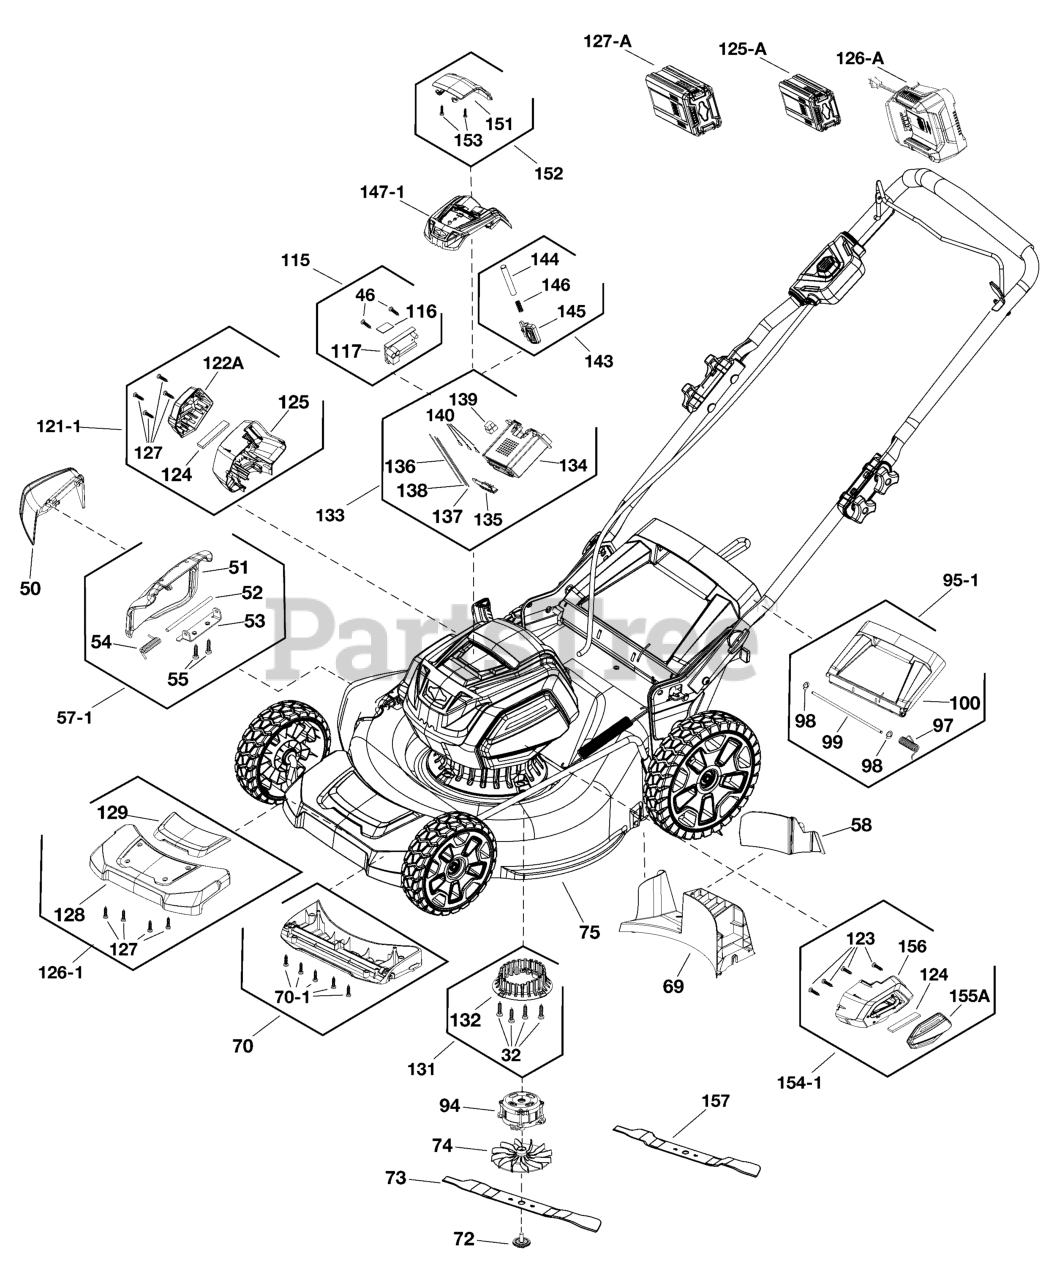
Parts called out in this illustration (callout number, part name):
32	SCREW
46	SCREW
50	KIT, Deflector, Side Discharge
51	COVER
52	SHAFT
53	BRACKET
54	SPRING, Torsion
55	SCREW
57-1	KIT, Cover
58	KIT, Mulch Plug
69	KIT, Back Bulkhead
70	KIT, Front Bulkhead
70-1	SCREW
72	KIT, Bolt
73	KIT, Blade
74	KIT, Fan
75	KIT, Mower Deck
94	KIT, Motor
95-1	KIT, Rear Cover
97	SPRING, Torsion
98	PIN, Cotter
99	SHAFT
100	COVER, Rear
115	KIT, PCB, NA
116	SENSOR
117	PCB
121-1	KIT, Cover, Right
122A	COVER, Right
123	SCREW
124	SCREEN, Dust
125	HOUSING, Right
125-A	* BATTERY, 2.0, 82V NA
126-1	KIT, Front Panel
126-A	* CHARGER, Battery, NA
127	SCREW
127-A	* BATTERY, 4.0, 82V NA
128	BUMPER
129	COVER, Bumper
131	KIT, Base
132	BASE
133	KIT, Housing, Battery, NA
134	HOUSING, Battery
135	INSERT
136	WIRE, Yellow
137	WIRE, Yellow
138	WIRE, Yellow
139	COVER
140	CONTACT
143	KIT, Battery Release
144	PIN
145	BUTTON, Battery Releasee
146	SPRING, Torsion
147-1	KIT, Top Cover
151	COVER, Battery
152	KIT, Battery Cover
153	SCREW
154-1	KIT, Cover, Left
155A	COVER, Left
156	HOUSING, Left
157	BLADE, Mulching, 21"
